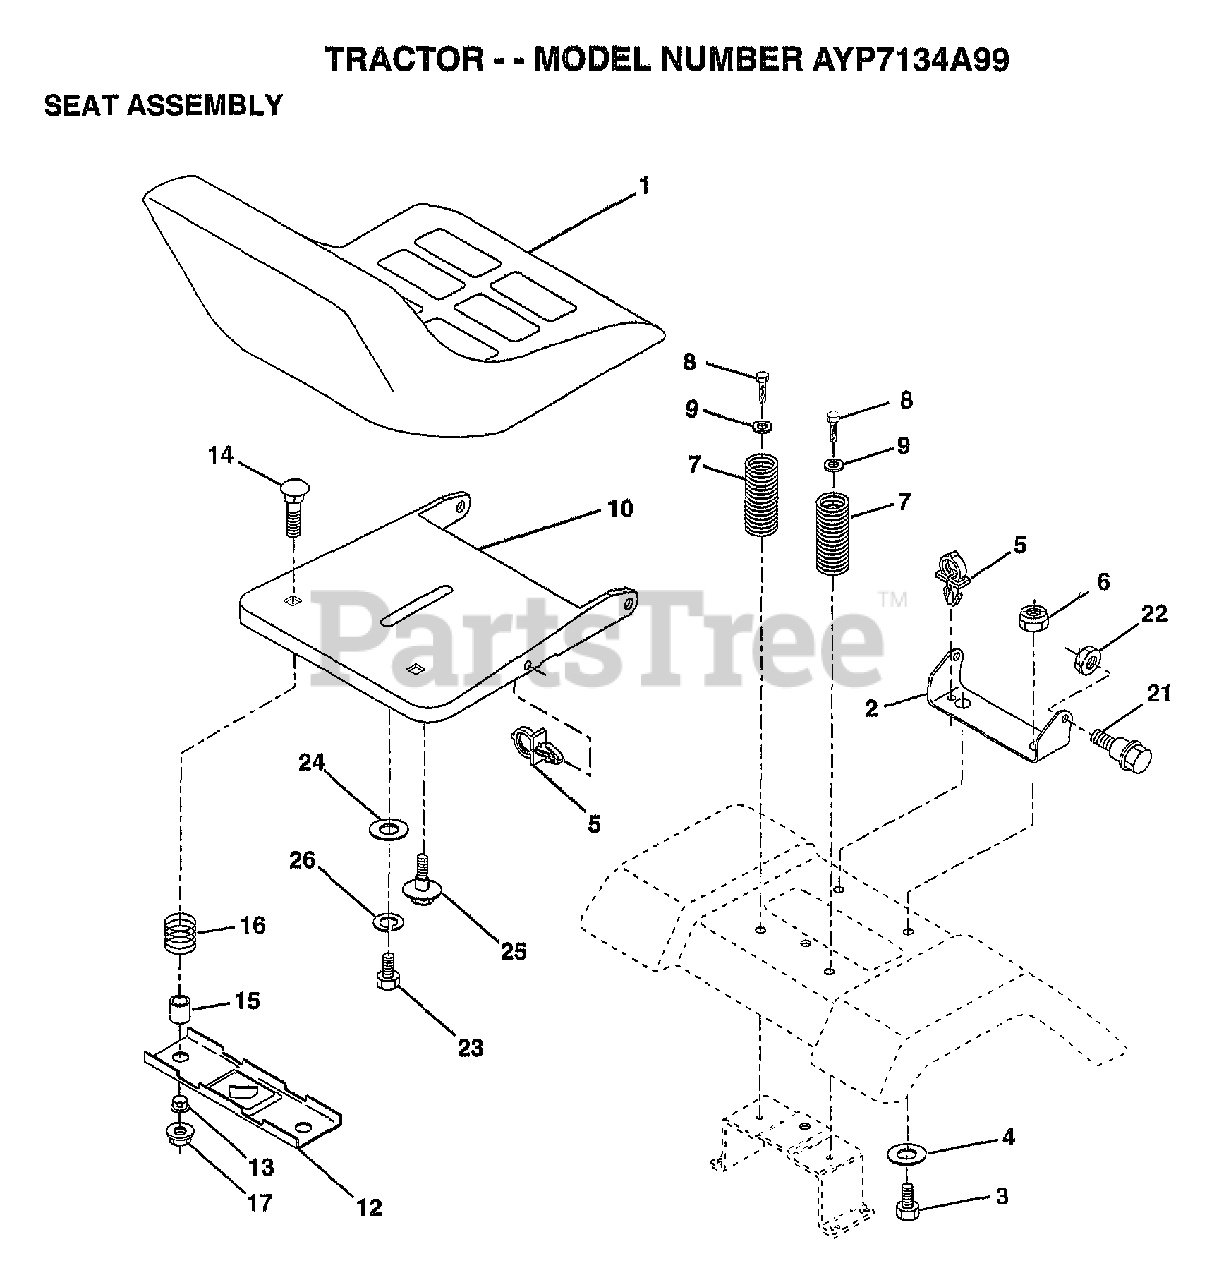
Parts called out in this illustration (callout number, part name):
2	BRACKET PVT SEAT
3	BOLT
4	WASHER PM
5	CLIP.PUSH-IN.HING
6	NUT
7	SPRING COMPRESSIO
8	SCREW GTV
9	WASHER
10	PAN-SEAT
12	BRKT SWITCH
13	BUSHING
14	BOLT-RD HD SQ NK
15	SPLIT SPACER
16	SPRING
21	"BOLT,SHOULDER"
22	NUT
23	BOLT
24	WASHER
25	"BOLT,SHOULDER"
26	LOCKWASHER
